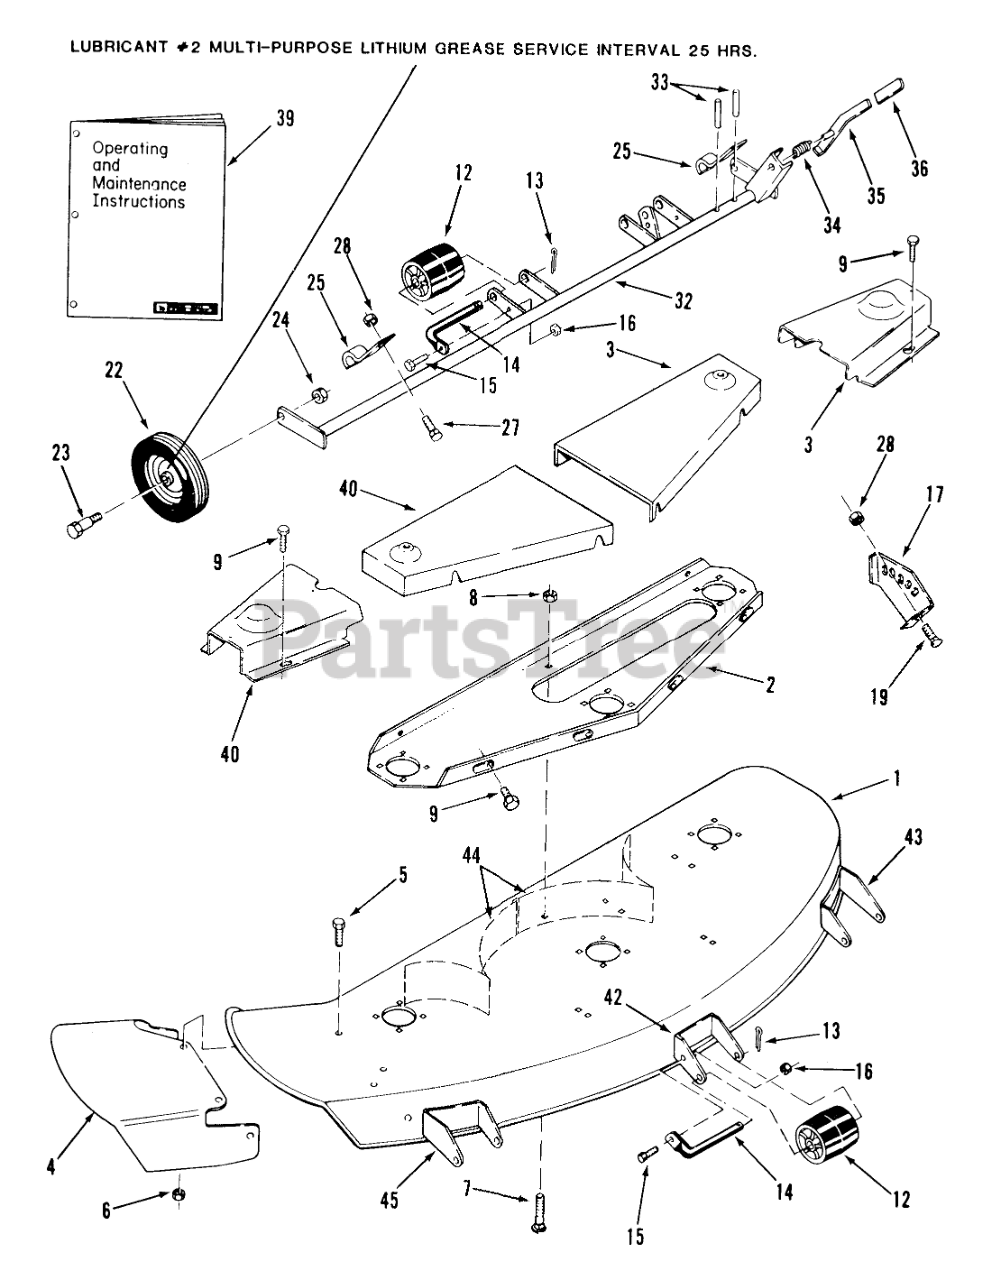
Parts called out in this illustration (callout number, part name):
1	Mower Deck-48 in.15-48SC
2	Channel
3	Belt Cover LH
4	GUARD WA - 48" CHUTE R (NS)
5	Bolt
6	Nut
7	Bolt-Carriage
8	NUT
9	Screw
12	Roller
13	Cotter Pin
14	ROLLER-SHAFT
15	Bolt
16	Nut
17	Quadrant
19	Bolt
20	SHAFT-ROLLER
22	WHEEL
23	BOLT-SHOULDER
24	Nut
25	Clamp
27	Bolt
28	NUT
32	Gage Wheel Support 15-48SC
33	PIN-SPIROL
34	SPRING-COMPRESSION
35	Lever
40	Belt Cover RH
42	BRKT-ROLLER
43	BRKT-ROLER R
44	BAFFLE-DECK LH
45	BRKT-ROLLER R
